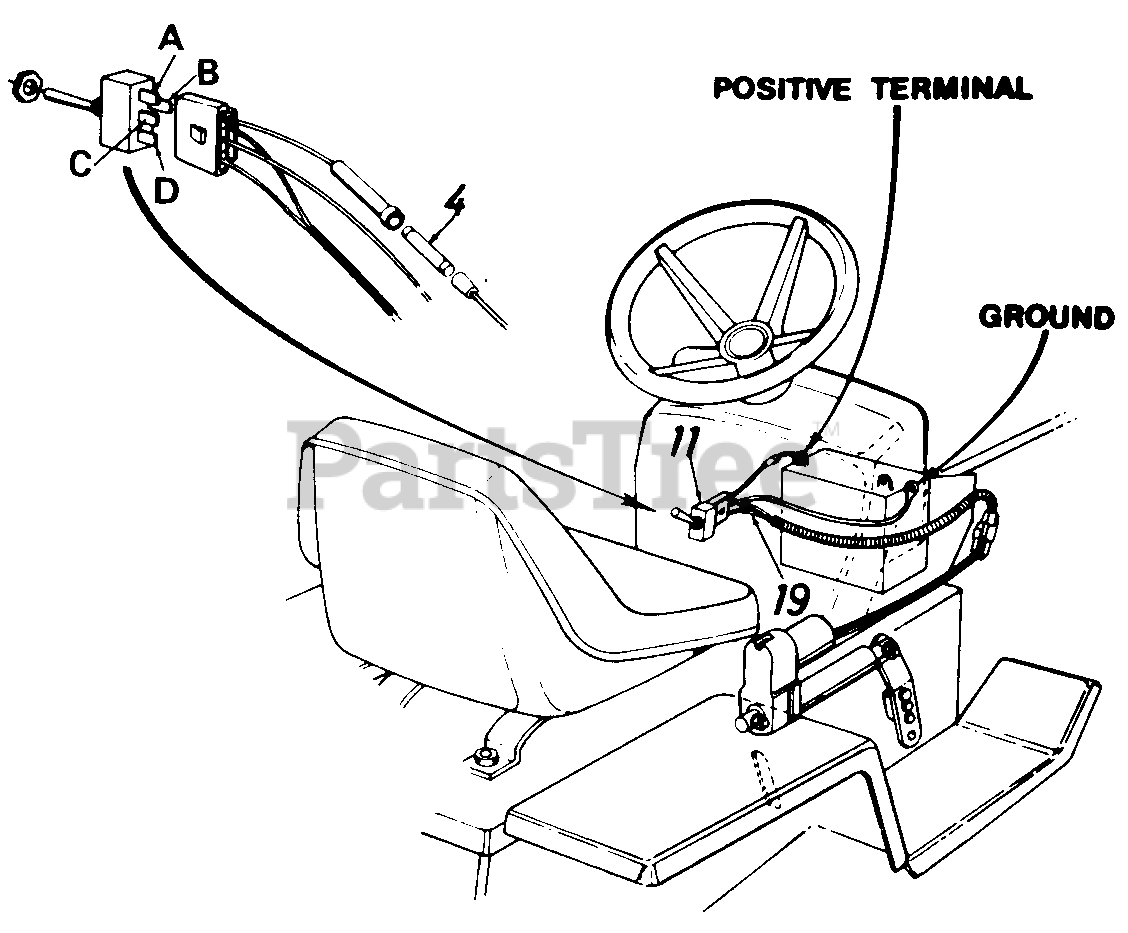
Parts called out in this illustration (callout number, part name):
4	Fuse 30 AMP
11	Toggle Switch
19	Wire Harness
A	Blue Wire Connects to Positive Terminal on Battery
B	Yellow Wire Connects to Actuator
C	Black Wire Ground Wir-to Frame
D	Red Wire Connects to Actuator
